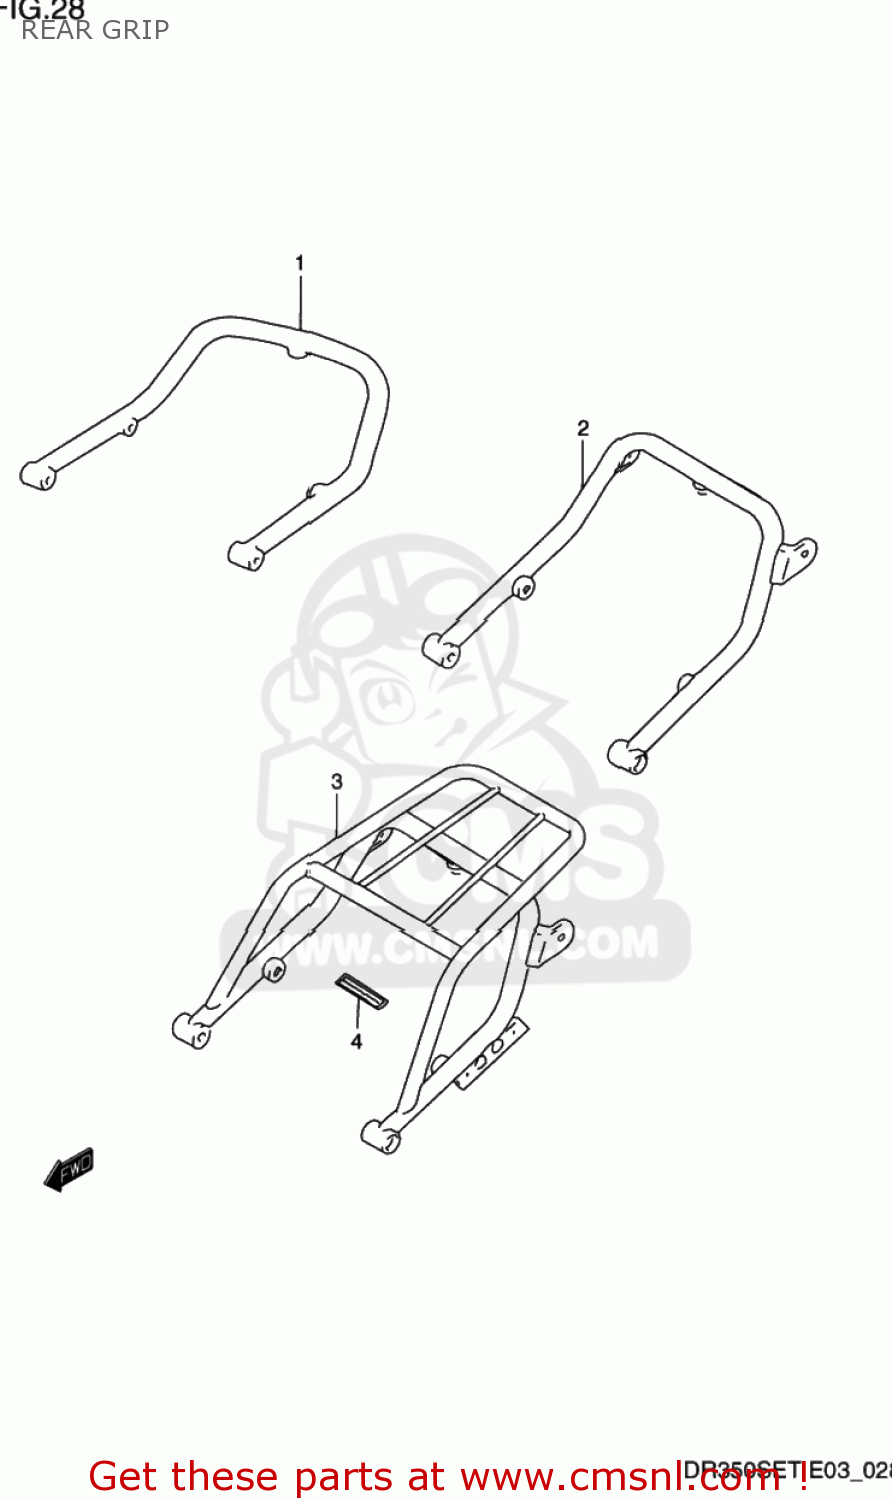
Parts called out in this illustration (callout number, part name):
1	GRIP COMP,REAR
2	GRIP,RR
3	CARRIER
4	LABEL,WARNING
